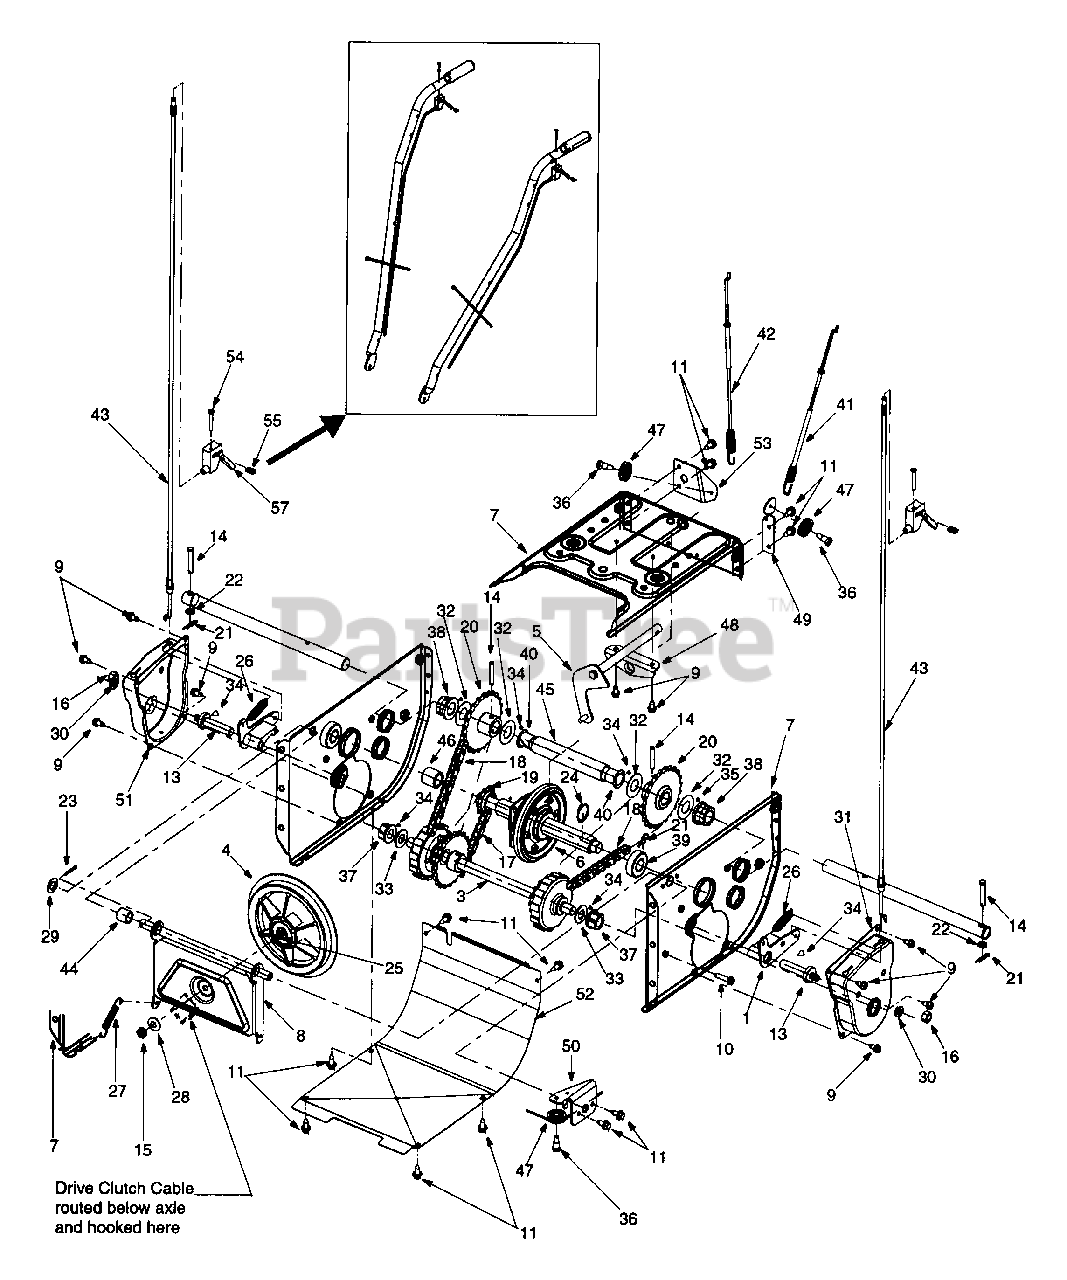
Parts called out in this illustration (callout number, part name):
1	Dogg Assembly: RH
2	Dogg Assembly: LH
3	Shift Assembly: Steerable Drive
4	Friction Wheel Disc Assy.
5	Shift Rod Assembly
6	Wheel Assembly, Friction
9	Hex Wshr Hd. TT Screw 1/4-20 x .5
10	Hex Wshr Hd. TT Screw 1/4-20 x 1
11	Hex Hd TT Scrw 1/4-20 x .625"
12	Drive Shaft
13	Actuator Shaft
15	Jam Nut 3/8-24 Gr.8
16	Hex Nut: 3/8-16
17	Chain
18	Chain
19	Sprocket: 10T
20	Sprocket
21	Cotter Pin
22	Flat Washer
23	Cotter Pin
24	Snap Ring
25	Adhesive: Loctite(R)
26	Extension Spring
27	Extension Spring
28	Bell Washer
29	Flat Washer
30	Lock Washer
31	Retainer Shaft LH: Actuator Drive
32	Flat Washer
33	Flat Washer
34	Lubricant
35	Grease
36	Shoulder Screw
37	Hex Flange Bearing
38	Hex Flange Bearing
39	Ball Bearing
40	Flange Bushing
41	Auger Clutch Cable
42	Drive Clutch Cable
43	Steering Cable
44	Spacer
45	Axle Support Tube
46	Spacer
47	Roller Cable
49	Auger Clutch Cable Guide Bracket
50	Front Support Guide Bracket
51	Retainer Shaft RH: Actuator Drive
54	Oval C-Sunk Machine Screw
55	Weld Nut
56	Cable Tie
57	Turn Trigger
58	Cotter Pin
59	Turn Trigger
